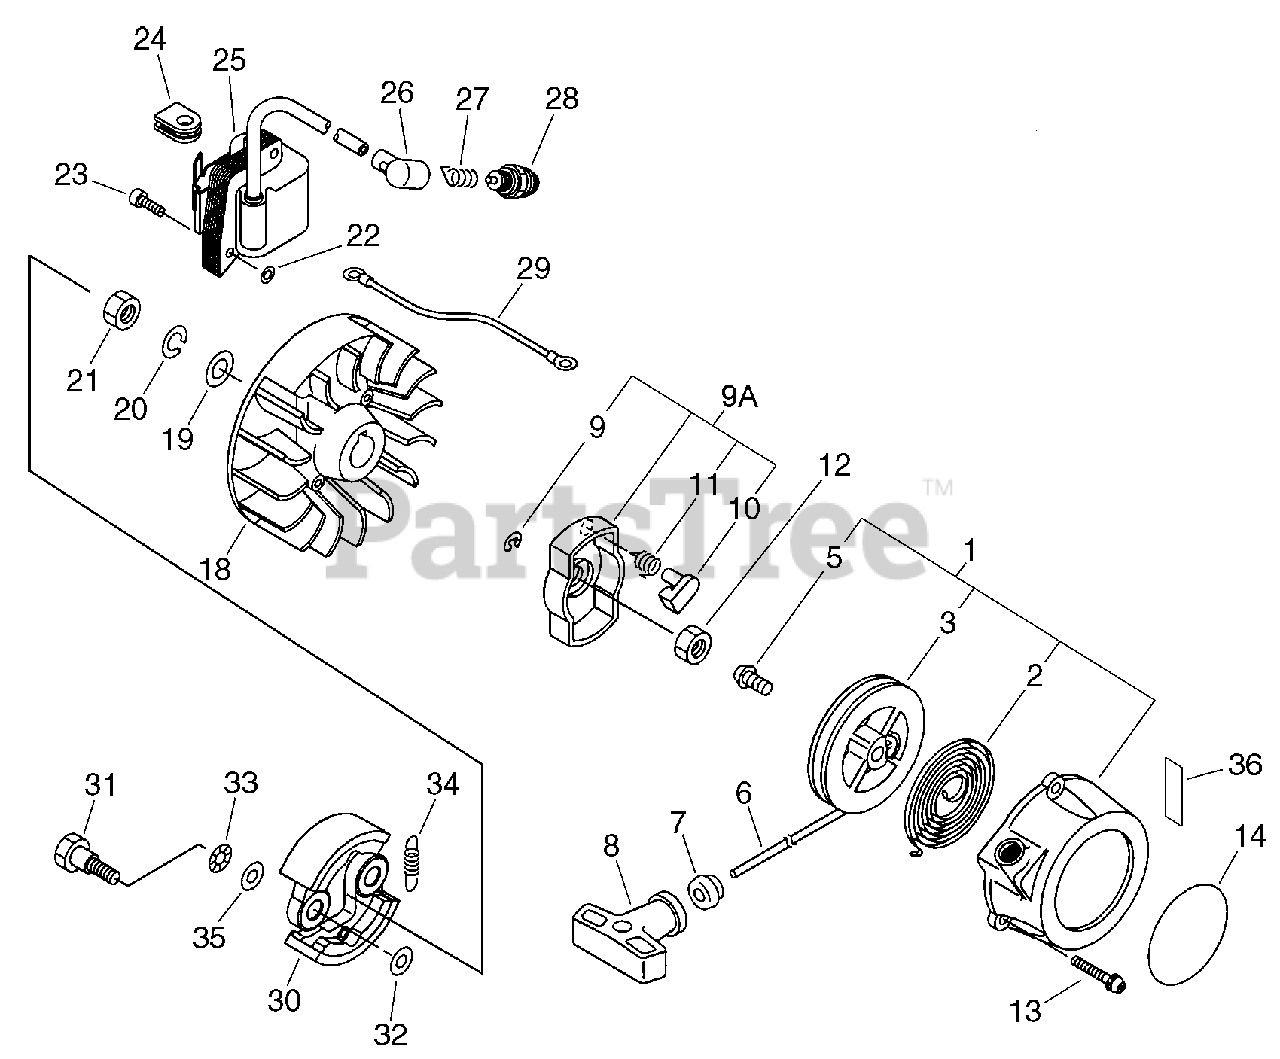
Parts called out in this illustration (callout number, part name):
1	STARTER ASSY
2	SPRING, REWIND
3	REEL, ROPE
6	ROPE, STARTER - 3.5X850
7	GUIDE, ROPE
8	GRIP, STARTER
9	RING, RETAINING - 4
9A	STARTER PAWL ASSY
10	PAWL, STARTER
11	SPRING, RETURN
13	SCREW - 4X14
14	LABEL - KIORITZ
18	FLYWHEEL
19	WASHER - 8
20	LOCKWASHER - 8
23	SCREW - 4X22
25	COIL, IGNITION
26	CAP, SPARK PLUG
27	TERMINAL, SPARK PLUG CAP
28	SPARK PLUG -- BPM-7Y
29	LEAD - GROUND
30	SHOE, CLUTCH
31	BOLT, CLUTCH
32	WASHER - 10
33	WASHER - SPRING
34	SPRING, CLUTCH
35	WASHER - 8
36	LABEL - HOT SURFACE
